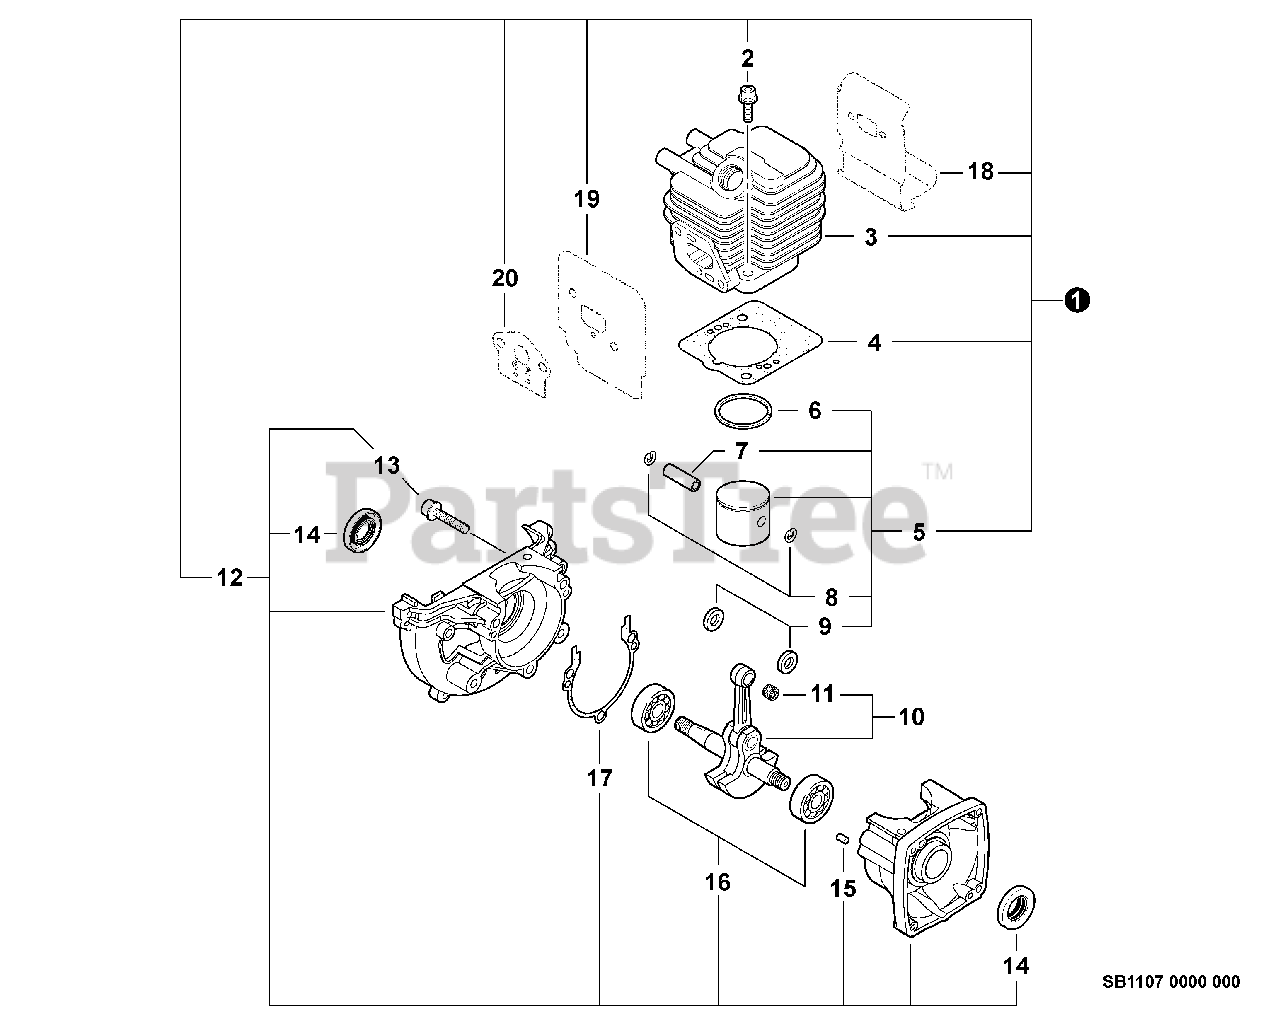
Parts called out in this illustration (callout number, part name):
1	SHORT BLOCK
2	BOLT 5×22
3	CYLINDER
4	GASKET, CYLINDER
5	PISTON KIT
6	RING, PISTON
7	PIN, PISTON 8
8	RING, SNAP
9	WASHER, THRUST
10	CRANKSHAFT ASSY
11	BEARING, NEEDLE 8
12	CRANKCASE KIT
13	BOLT 5×28
14	SEAL, OIL 12
15	PIN, LOCATING 4×8
16	BEARING, BALL - 6201 C3
17	GASKET, CRANKCASE
18	SHIELD, EXHAUST
19	SHIELD, INTAKE
20	GASKET, INTAKE
